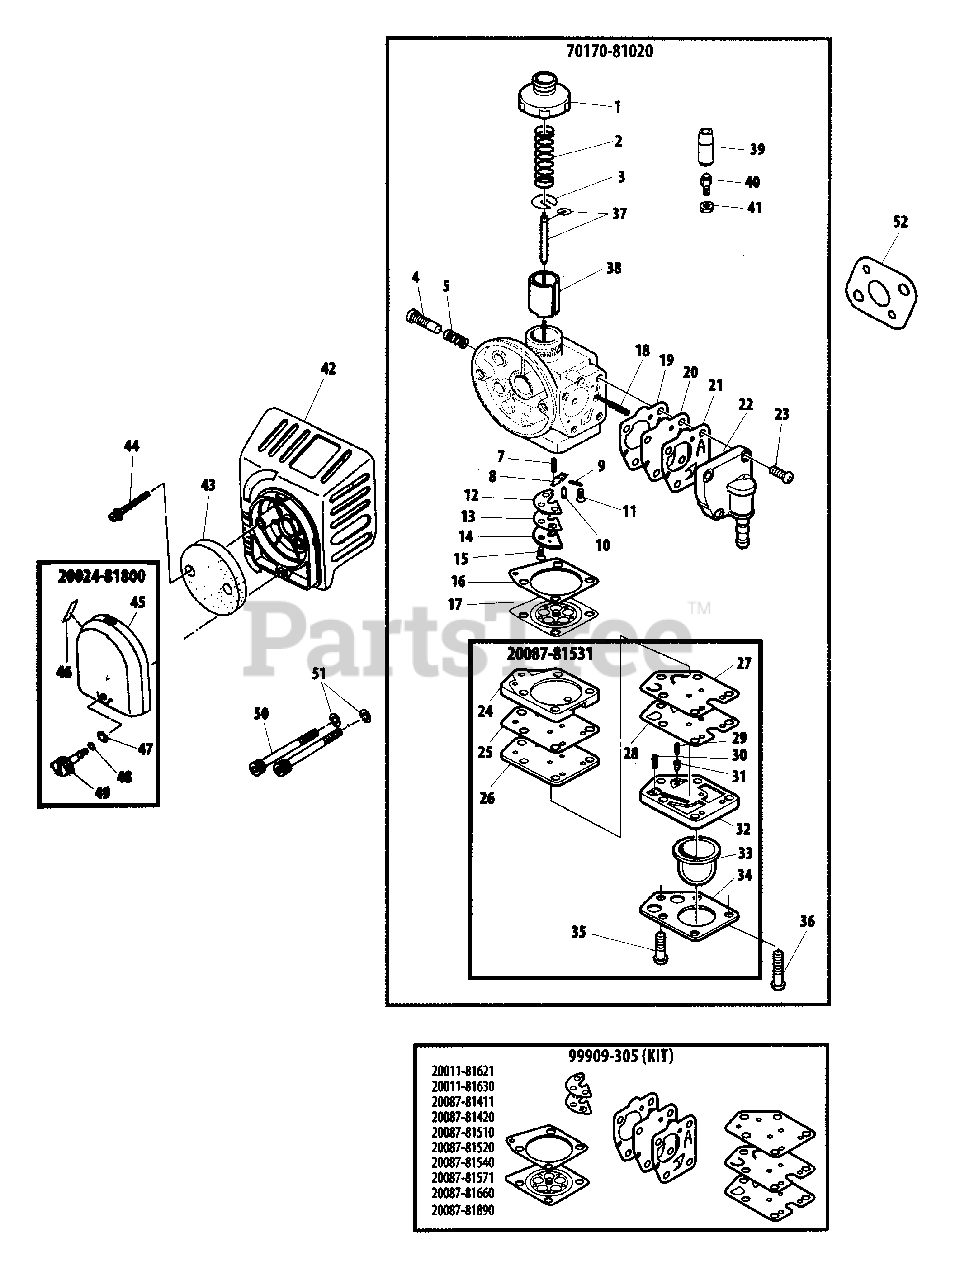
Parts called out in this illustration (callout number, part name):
1	CAP, CARBURETOR
2	SPRING
3	WASHER, SPRING SUPPORT
4	SCREW, IDLE ADJUST
5	SPRING
7	SPRING
8	LEVER, METERING
9	PIN, METERING LEVER
10	VALVE, INLET NEEDLE
11	SCREW M3×8
12	GASKET
13	VALVE, CHECK
14	PLATE
15	SCREW M3×8
16	GASKET, METERING DIAPHRAGM
17	DIAPHRAGM, METERING
18	SPRING, COIL
19	GASKET, DIAPHRAGM
20	DIAPHRAGM, METERING
21	VALVE, PUMP
22	PUMP BODY
23	SCREW
24	COVER, PUMP
25	GASKET
26	PLATE, PUMP
27	VALVE, CHECK
28	GASKET
29	SPRING
30	SPRING
31	VALVE, CHECK
32	COVER, PUMP
33	BULB, PURGE
34	RETAINER, PURGE BULB
35	SCREW
36	SCREW 3×20
37	NEEDLE, JET
38	SLIDE VALVE
39	GROMMET
40	ADJUSTER, CABLE
41	NUT, LOCK
42	CASE, AIR FILTER
43	FILTER, AIR
44	SCREW
45	COVER, AIR FILTER
46	LABEL, CHOKE
47	WASHER, CONE M6
48	O-RING
49	THUMBSCREW
50	BOLT M5×65
51	LOCKWASHER
52	GASKET, INTAKE
20024-81800	AIR FILTER COVER ASSY
20087-81531	PURGE PUMP KIT
70170-81020	CARBURETOR - DPV10W-18B
99909-305	DIAPHRAGM/GASKET KIT
